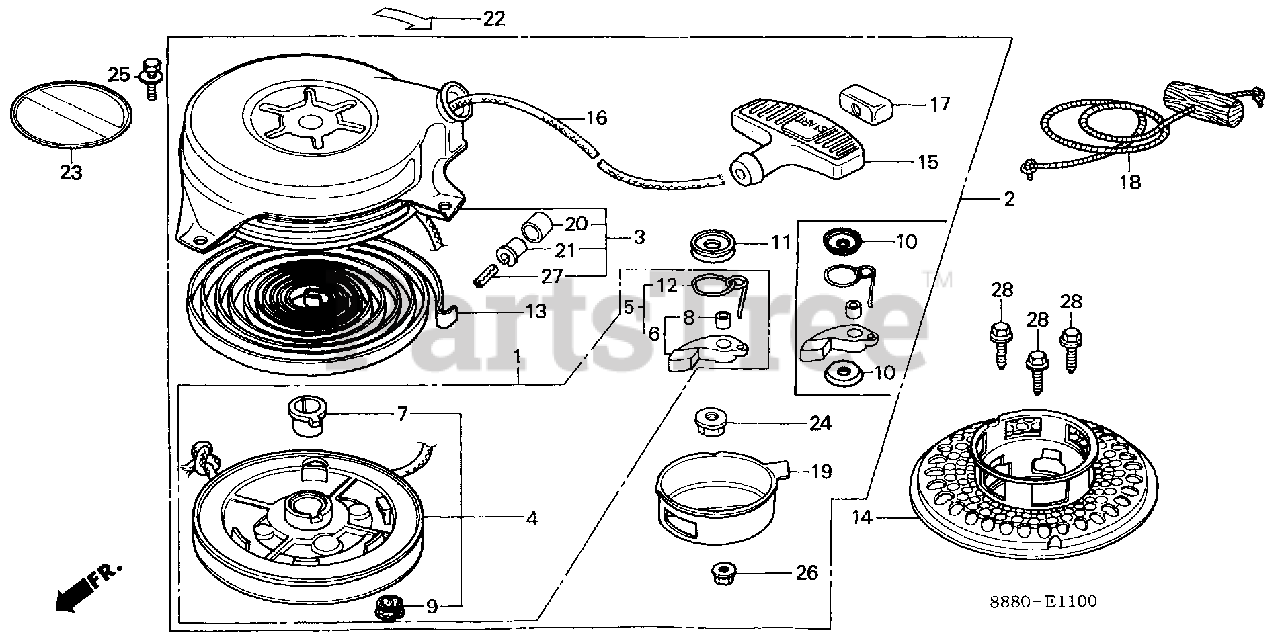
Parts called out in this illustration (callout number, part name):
1	REEL KIT, STARTER
2	STARTER ASSY., RECOIL *NH67* (SPARKLE WHITE)
2	STARTER ASSY., RECOIL *NH67* (SPARKLE WHITE) (NOT AVAILABLE)
3	CASE, STARTER *NH67* (SPARKLE WHITE)
4	REEL KIT, STARTER
4	REEL, STARTER
5	RATCHET KIT
7	BOSS, REEL
8	BUSH, RATCHET
9	BUSH, REEL STARTER
10	PLATE, FRICTION
11	PLATE, FRICTION
12	SPRING, FRICTION
13	SPRING, RETURN
14	PULLEY, STARTER
15	GRIP, STARTER
16	ROPE, RECOIL STARTER
17	SUPPORT, GRIP
18	ROPE, STARTER
19	COVER, STARTER REEL
20	ROLLER, GUIDE
21	BUSH, ROLLER
24	NUT, SELF-LOCK (8MM)
25	BOLT, FLANGE (6X8)
26	NUT, FLANGE (5MM)
27	PIN, SPRING (3X18)
28	BOLT, FLANGE (6X16)
